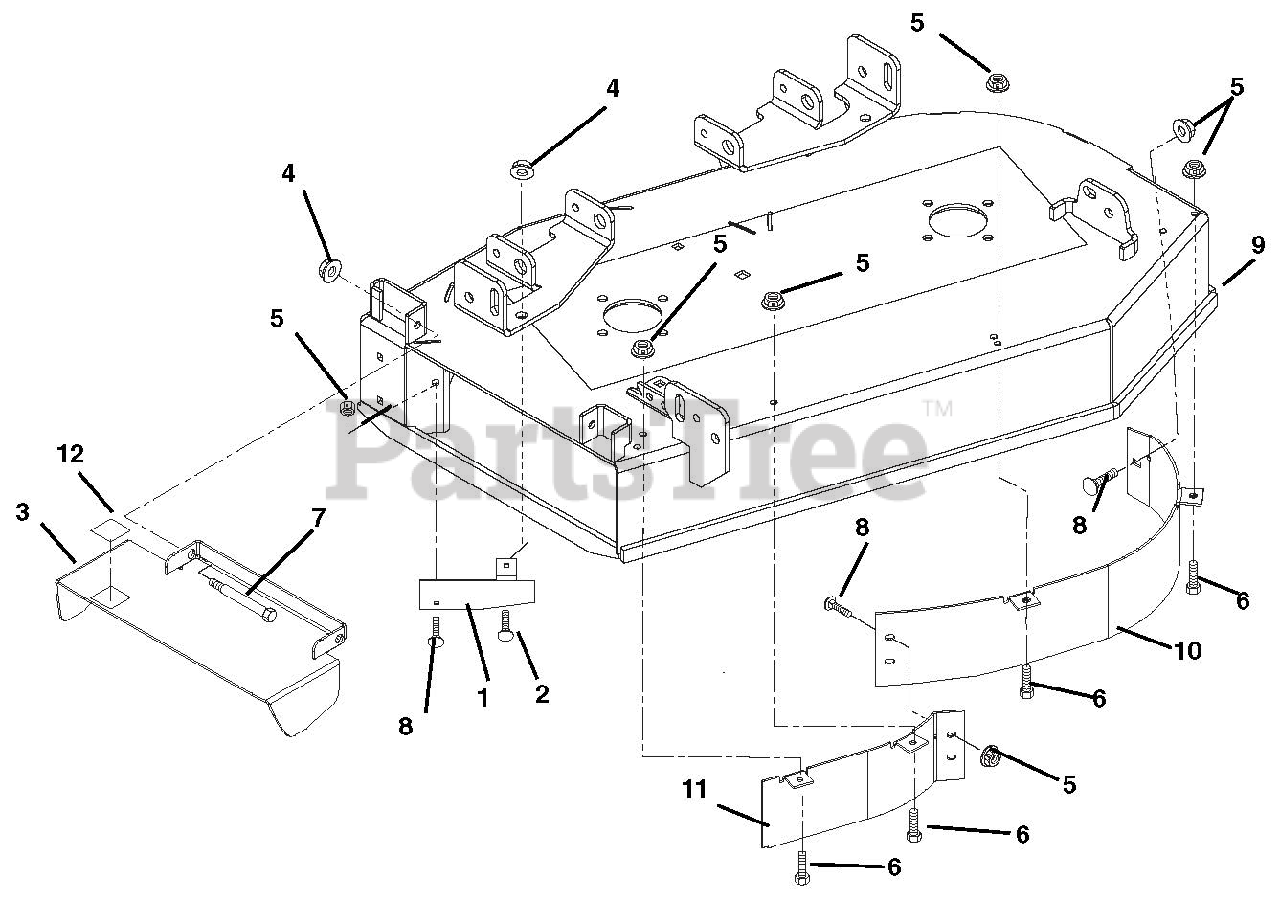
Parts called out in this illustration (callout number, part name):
1	Baffle, Deflector
2	Bolt, Round Head Square Neck .38-16 x 1.25 Grade 5
3	Chute, Discharge
4	Nut, Nyloc Flange 3/8-16
5	Nut, Nyloc Flange 5/8-18
6	Bolt, Hex .31-18 x .75 Grade 5
7	Bolt, Shoulder .38-16 x .50 Socket Head
8	Bolt, Round Head Square Neck .31-18 x .75 Grade 5
9	Weldment, 34" Side Discharge Deck
10	Baffle, 34" Front Left Hand
11	Baffle, 34" Front Right Hand
12	Grip, Pedal 1.50 x 3.00
